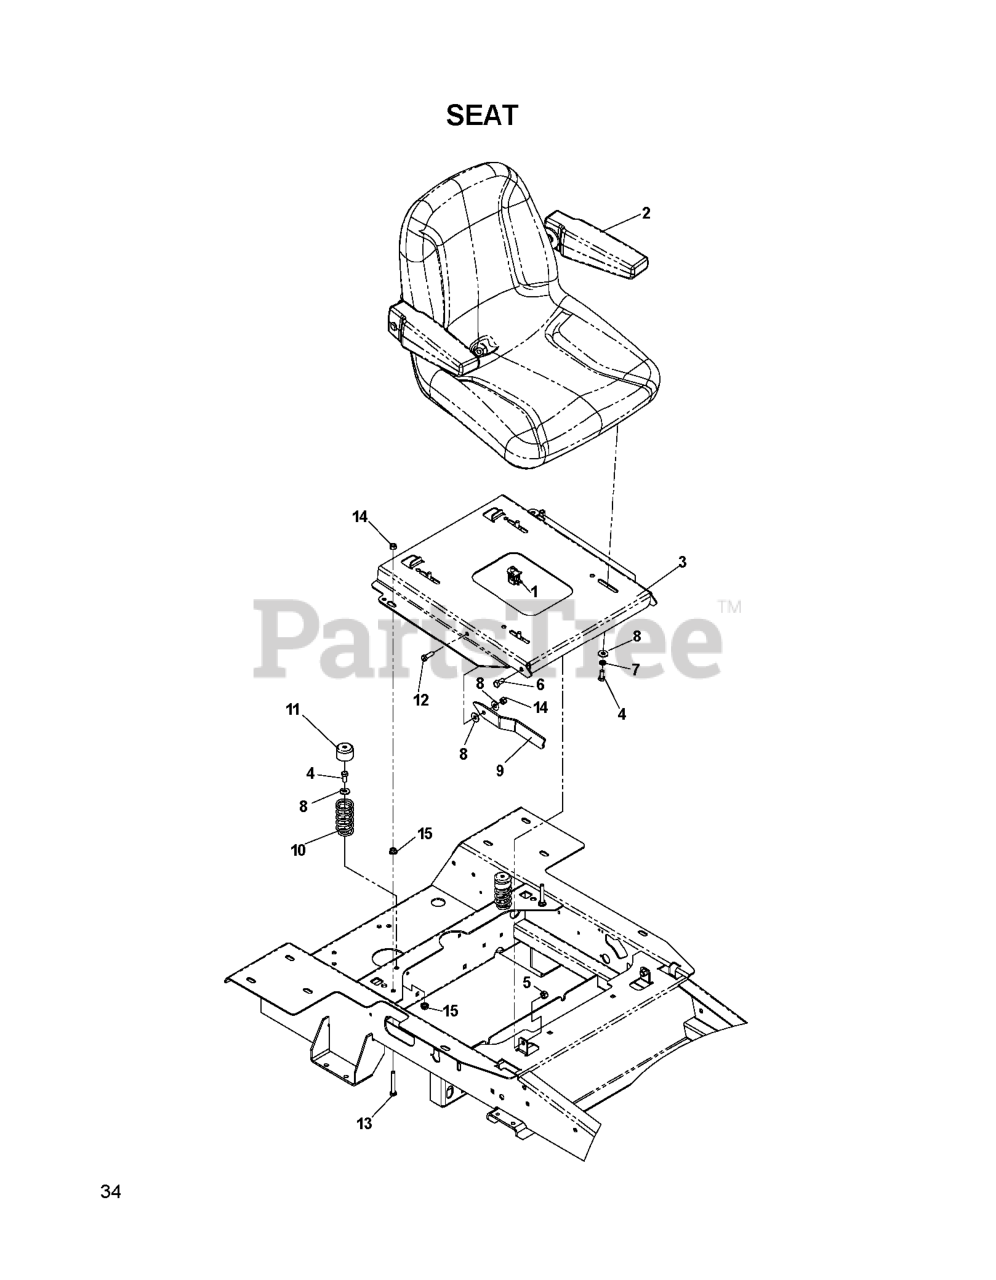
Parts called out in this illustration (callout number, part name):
1	SEAT.TH151.GREY.PREM.HUSQ.MI
2	BRKT.PIVOT.FENDER
3	STRAP
6	NUT
7	SPRING COMPRESSION
8	BOLT.5/16-18UNCX3/4 W/SEMS.BLK
10	PAN.ASM.SEAT.3PT
21	BOLT.SHOULDER.5/16-18
37	NUT.71038.31-18.HEX.NYLOCK
40	HANDLE SLIDE SEAT
41	SPRING.LATCH.SEAT.TEX
44	WASHER 13/32 X 2-3/8 X 12GA
